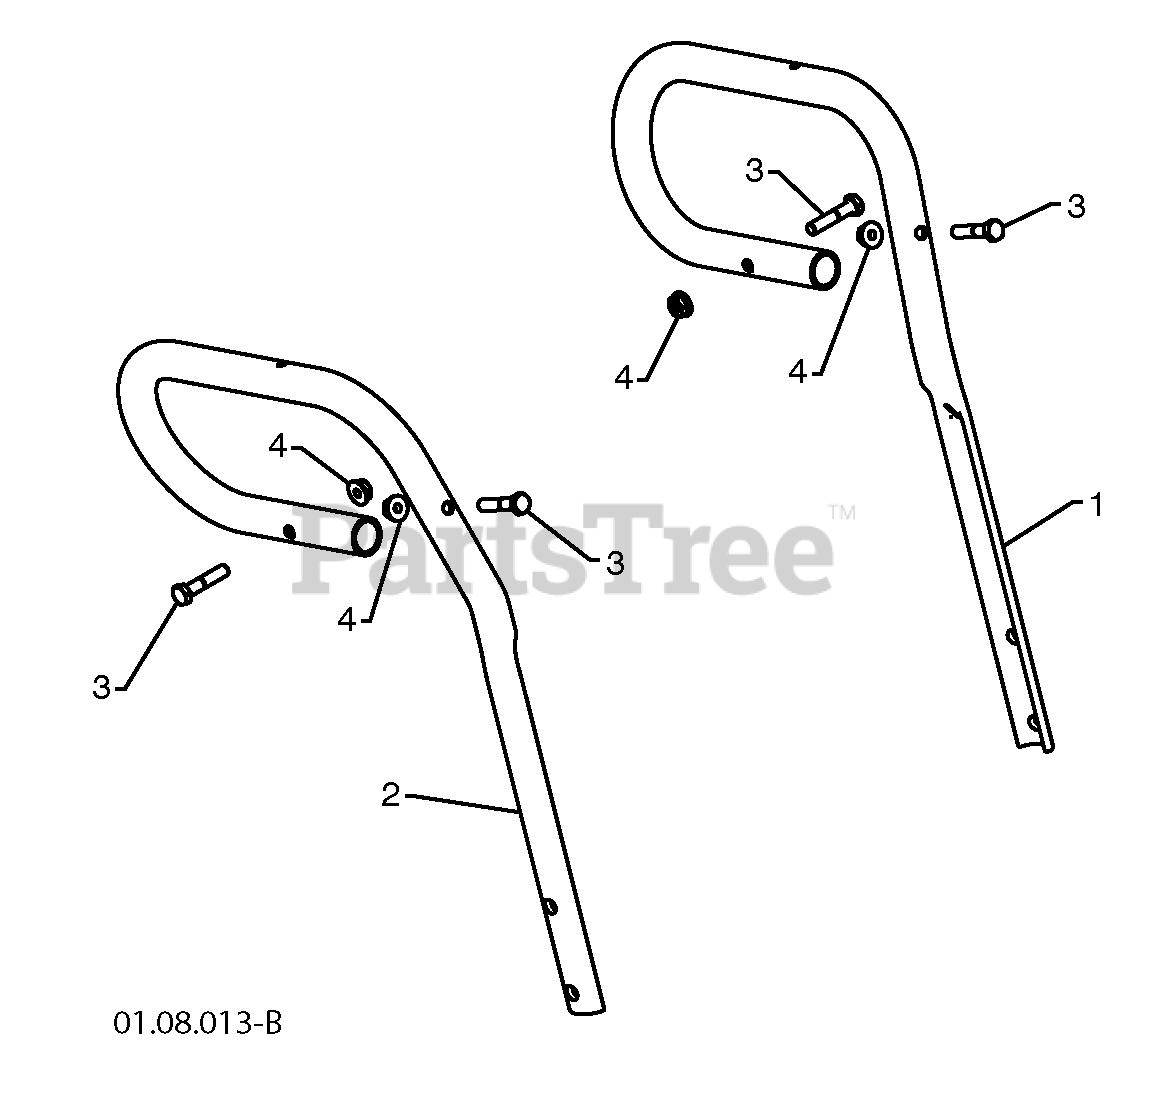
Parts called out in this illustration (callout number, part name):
1	Loop Handle Lh
2	Loop Handle Rh
3	Screw 5/16-18 X 1.50
4	Nut 5/16-18
